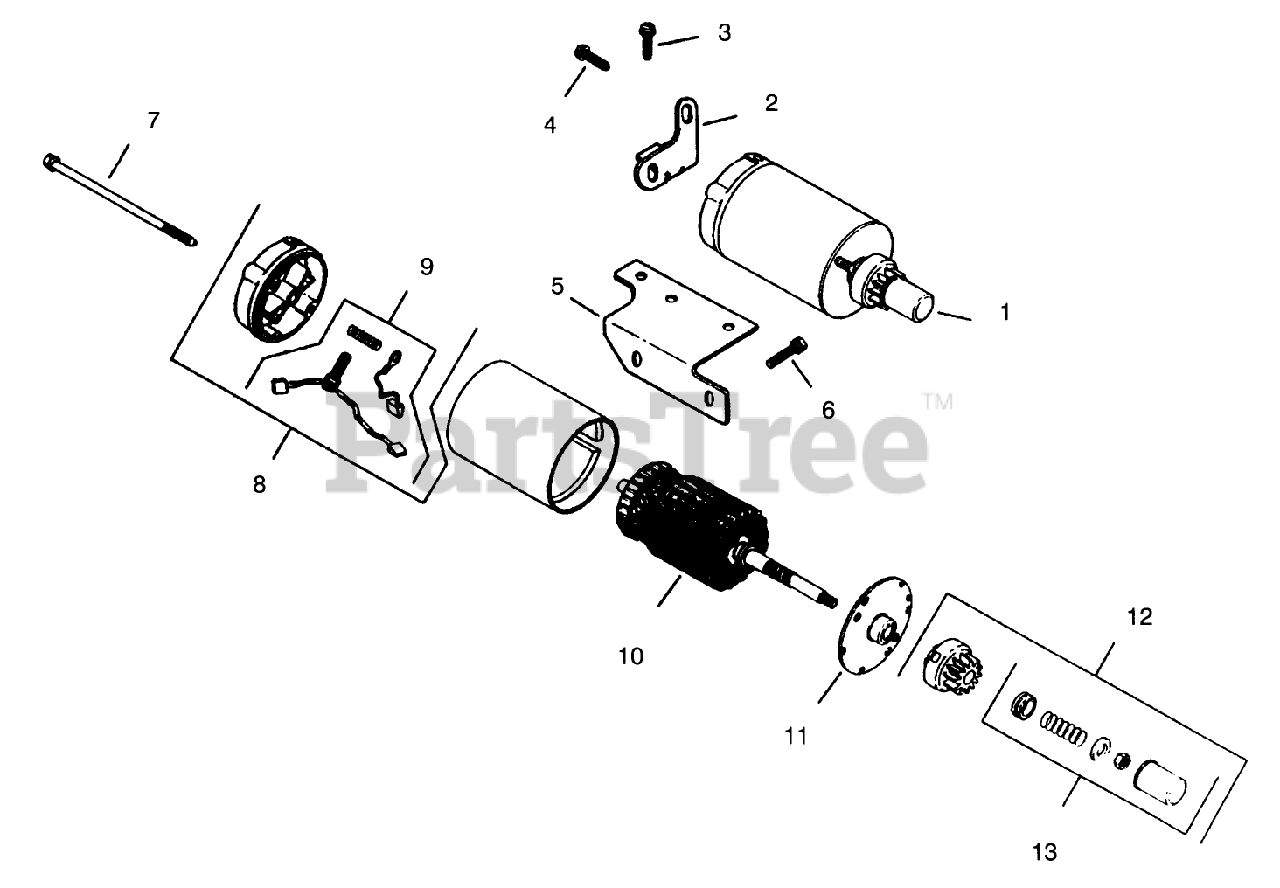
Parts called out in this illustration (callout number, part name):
1	Starter Assembly (Includes Items 9 thru 15)
2	KOHLER 45-126-17
3	KOHLER X-67-62
4	KOHLER X-67-83
5	KOHLER 47-126-29
6	KOHLER X-159-2
7	KOHLER 41-086-19
8	KOHLER 41-227-04
9	VNDR #52-755-15
10	KOHLER 47-170-02
11	KOHLER 41-227-03
12	KOHLER 47-755-07
13	KOHLER 47-755-13
